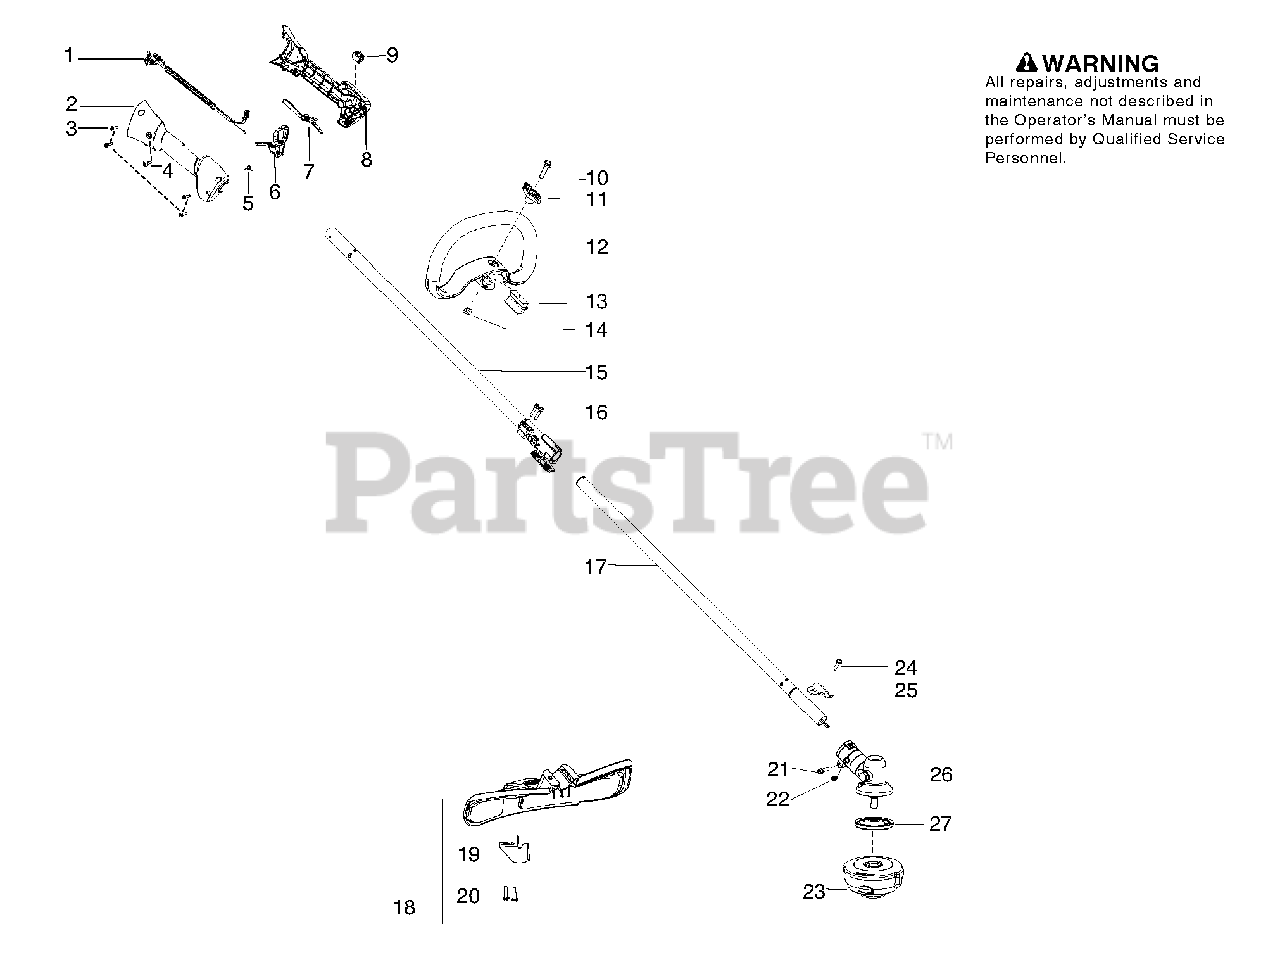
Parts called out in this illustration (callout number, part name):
1	Assy-Cable/Wire Harness
2	Housing-Throttle (RH)
3	Screw
4	Screw
5	Spring-Trigger
6	Trigger
7	Lockout-Throttle
8	Housing-Throttle (LH)
9	Kit-Switch
12	Assy - Loop Handle
14	Nut - Square M6
15	Kit-Driveshaft Upper
17	Kit-Lower Shaft
18	Kit-Shield
19	Limiter-Line
23	Assy-T25 Cutting Head
25	Bracket-Shield
26	Assy-Gearbox
27	Driver Disc
